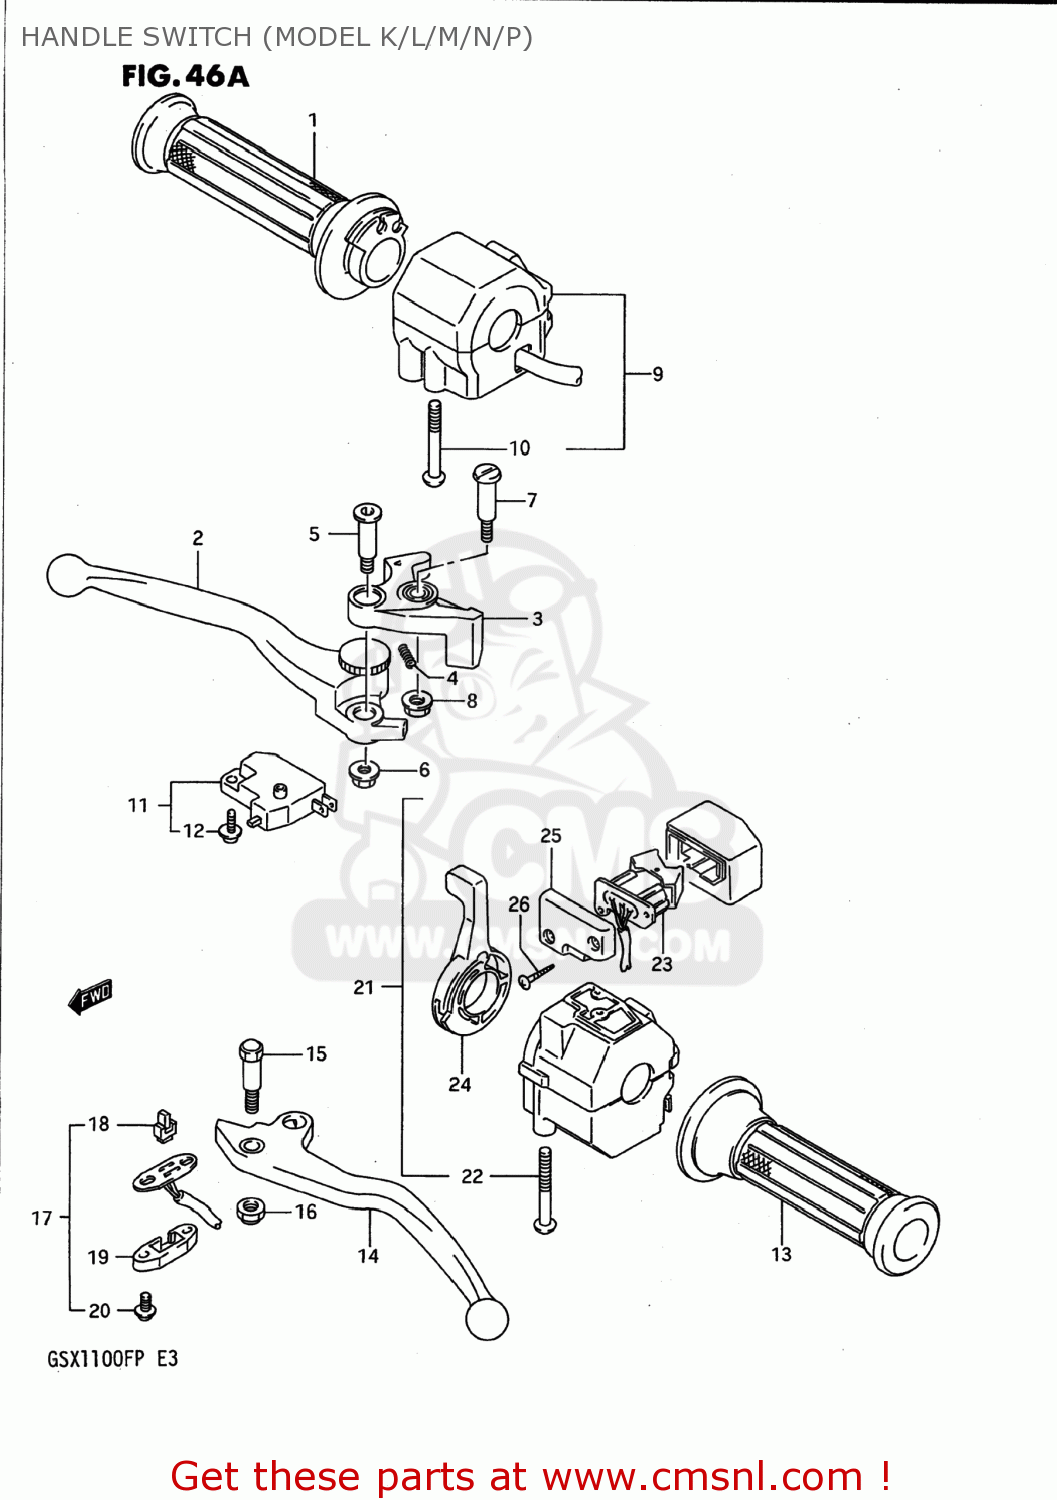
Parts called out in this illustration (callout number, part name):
1	GRIP,THROTTLE
2	LEVER,ADJUST
3	KNOCKER
4	SPRING
5	BOLT,LEVER
6	NUT
7	BOLT,LEVER PIVOT
8	NUT 6MM
9	SWITCH ASSEMBLY,HANDLE,RIGHT
10	SCREW, 5X45
11	SWITCH ASSEMBLY,STOP
12	SCREW
13	GRIP,L
14	LEVER,CLUTCH
15	BOLT,LEVER
16	NUT
17	SWITCH ASSEMBLY,CLUTCH
18	CONTACT,SWITCH
19	COVER,FR BK TERMINAL BASE
20	SCREW
21	SWITCH ASSEMBLY,HANDLE,LEFT
22	SCREW, 5X45
23	SWITCH,SCREEN
24	LVER,CHOKE
25	COVER,SCREEN SWITCH
26	SCREW,SCREEN SWITCH
